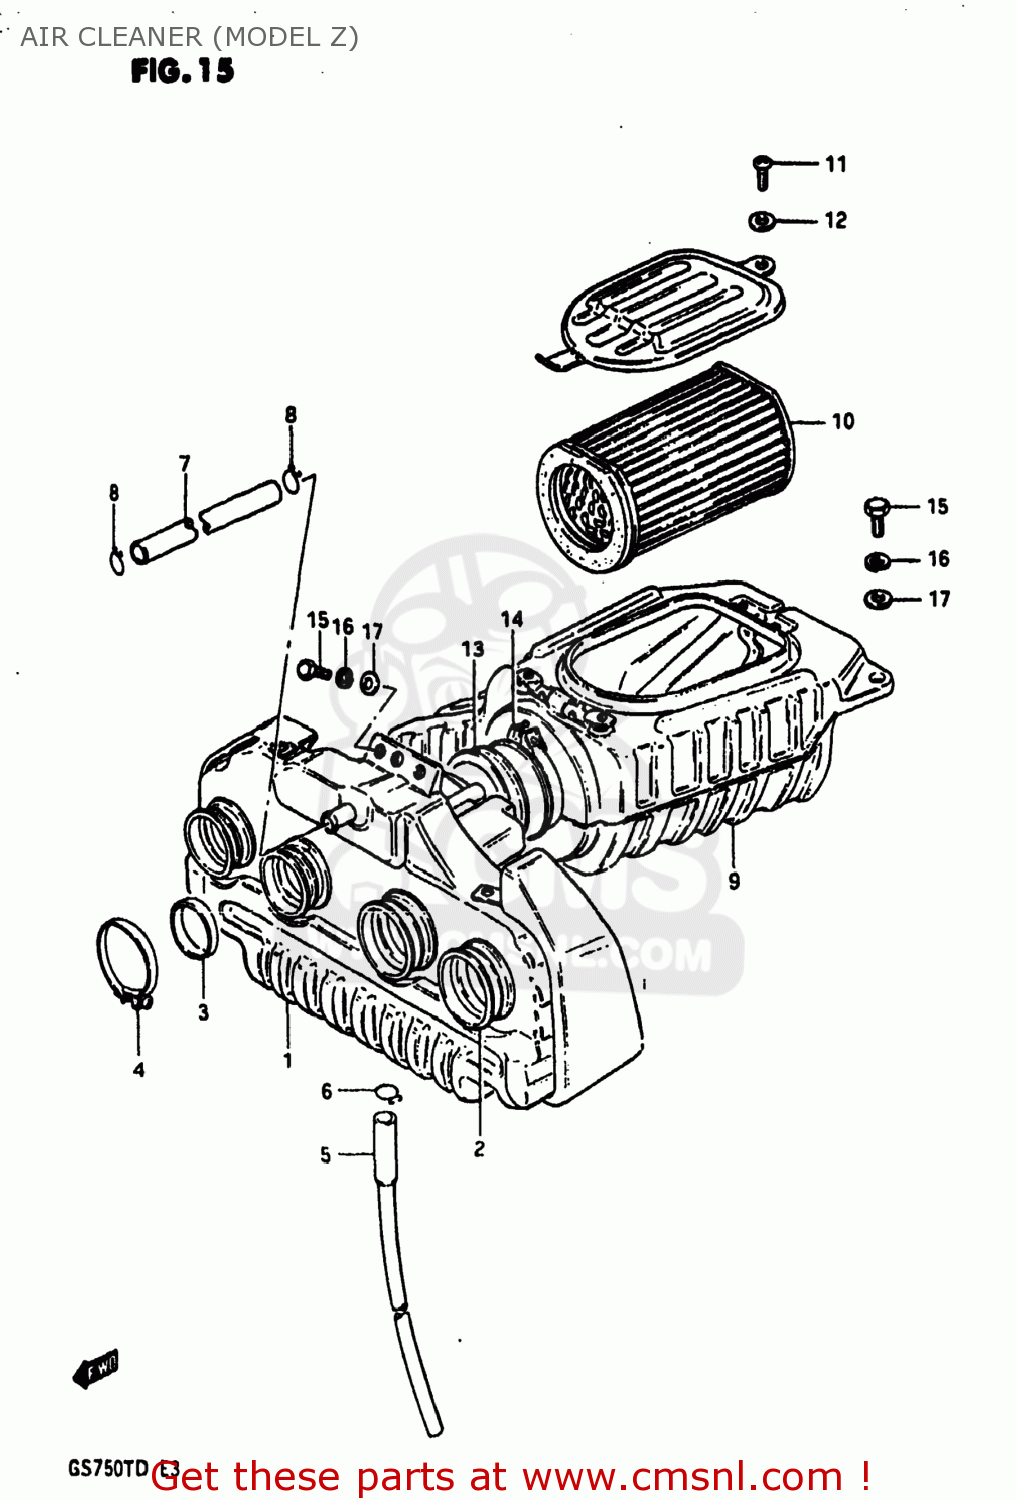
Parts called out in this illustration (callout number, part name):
1	CASE COMP,AIR CLEANER
2	TUBE,OUTLET
3	RING
4	CLAMP
5	DRAIN TUBE
6	CLIP
7	TUBE,BREATHER
8	CLIP
9	CLEANER SET,AIR,REAR
10	FILTER,AIR CLEANER
11	SCREW
12	WASHER
13	HOSE,AIR CLEANER
14	BAND
15	BOLT
16	LOCK WASHER
17	WASHER
